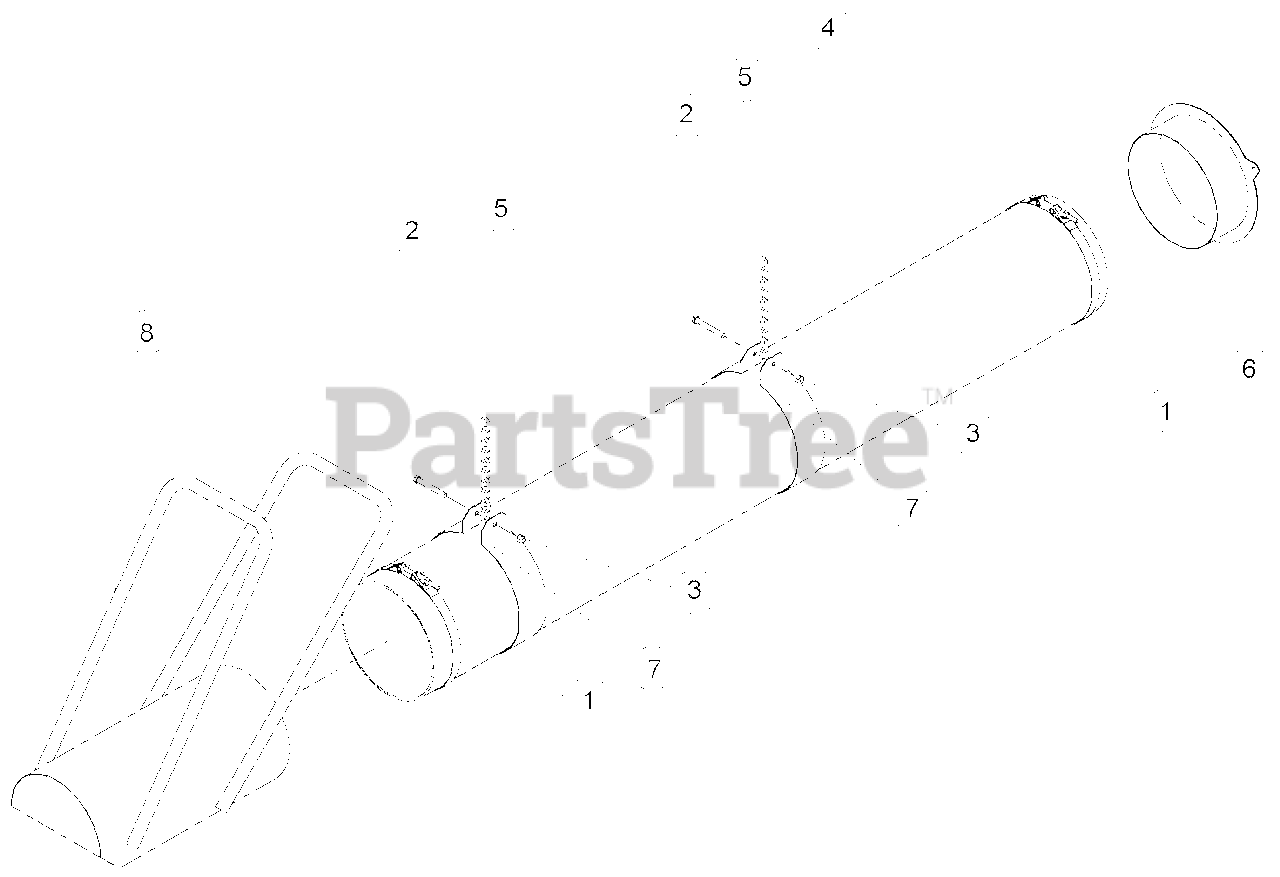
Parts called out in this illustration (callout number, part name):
1	CLAMP, 10.50 T-BOLT HOSE
2	BOLT, 3/8 NC X 3-1/2 HEX HD
3	NUT, 3/8" NYLOCK
4	HOSE, 10 IN X 12.5 FT INLET
5	CHAIN, HOSE SUPPORT
6	WELDMENT, INLET ADAPTER
7	WRAP, HOSE SUPPORT
8	WELDMENT, HOSE INLET
